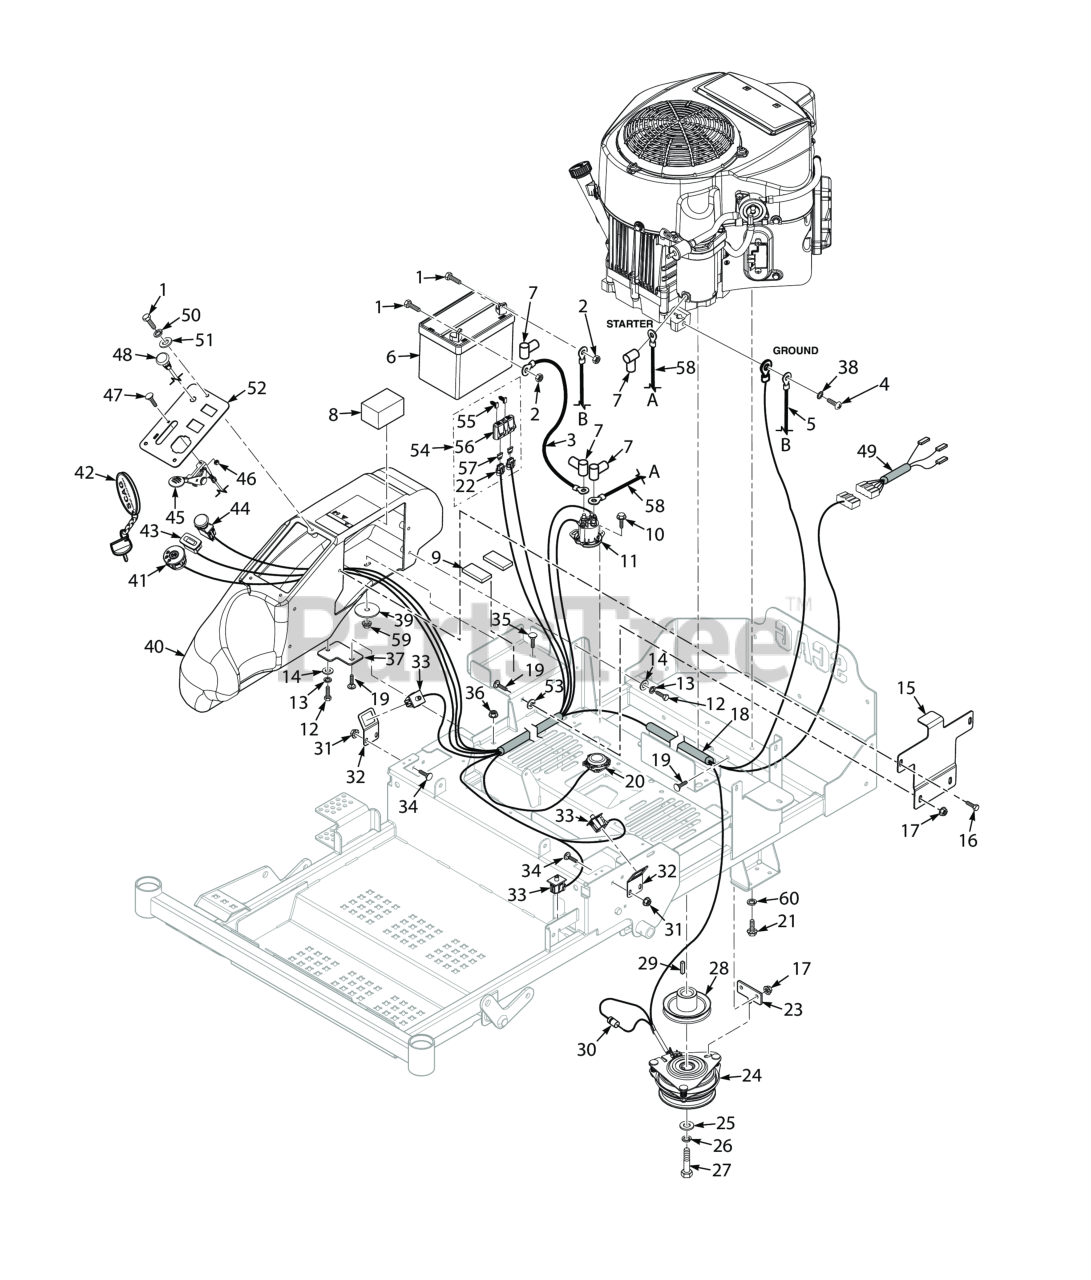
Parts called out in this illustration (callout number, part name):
1	Bolt, Hex Head 1/4-20 x .5" Battery, (Not Available Through Scag)
2	Nut, 1/4 - 20 Hex
3	Battery Cable, 18" Red w/Braid (25KA, 26DFI, 31DFI) - Kawasaki
4	Bolt, Hex Head M8 - 1.25 x 16 (48V / 52V)
5	Battery Cable, 31-1/2" Black (25KA, 26DFI, 31DFI) - Kawasaki
6	Battery, 12v - 230CCA
7	RUBBER BOOT
8	Pad, Battery - Rubber
9	Pad, Battery - Rubber
10	Screw, Self-Tapping 1/4-20 x 3/4
11	Solenoid, Sealed (Briggs & Stratton)
12	BOLT, SERRATED FLANGE HEX HEAD 5/16-18 X 3/4"
13	Lockwasher, 5/16 (.317 x .586 x .078) Helical Spring
14	Flatwasher, 5/16-.375 x .875 x .083 (35BV & 37BV-EFI)
16	CAP SCREW, 5/16-18 X 1/2" SERRATED FLANGE HEX
17	Nut, Flange Head Elastic Stop 5/16-18
18	Wire Harness
19	Bolt, 5/16-18 x .75 RHSN Carriage
20	Switch, Double Pole - Twist
21	Bolt, Hex Head 3/8-16 x 1-1/4", Kawasaki FX / FS
22	Fuse Holder Assembly
23	Plate, Anti-Rotation
24	Electric Clutch Assembly
25	Flatwasher, 7/16-.469 x 1.75 x .25 (48, 52)
26	Lockwasher, 7/16� Spring
27	Bolt, Hex Head 7/16-20 x 3¼" w/Patch
28	Pulley, 4-1/2" - 1" Bore
29	Key, 1/4 x 1/4 x 1.25" Pulley Mtg.
30	Diode, 600V 6 Amp
31	Nut, Flanged Elastic Stop 1/4-20
32	Bracket, Switch
33	Switch, Double Pole - Plunger
34	Serr. Fl. Hex Head CPSCR, 1/4-20 x 3/4"
35	Bolt, Carriage 5/16-18x1" (large frame units only)
36	Nut, Serrated Flange 5/16-18 (Right Front Engine Mounting, Briggs and Kohler Only)
37	Mounting Bracket, Fuel Tanks Front
38	Lockwasher, 5/16" Ext. Tooth (Kohler x1)
39	Flatwasher, 3/8-.406 x 2.25" x .1875
40	Console Tank, SZL
41	Ignition Switch
42	Key, Assembly w/Fob
42	Key w/Shroud Only
43	Hourmeter
44	Switch, PTO - 10 Amp
45	Throttle Control, Kawasaki
46	Nut, Elastic Stop #10-24
47	Bolt, Carriage #10-24 x 1/2"
48	Choke Control, Kawasaki
50	Lockwasher, 1/4� Spring
51	Flatwasher, 1/4" (.312 x .750 x .065")
52	Instrument Panel w/Decal
53	Nut, Push-On 5/16-18
54	Double Fuse Assy.
55	Clip, Fuse Holder
56	Cover, Sealed Double
57	FUSE, 20 AMP BLADE TYPE AUTOMOTIVE
58	Battery Cable, 18" Red w/Braid (25KA, 26DFI, 31DFI) - Kawasaki
58	Battery Cable, 25" Red (Kawasaki)
59	HEX NUT, ELASTIC STOP LOCK, 5/16-18
60	Lockwasher, 3/8" Spring, Kawasaki FX / FS
